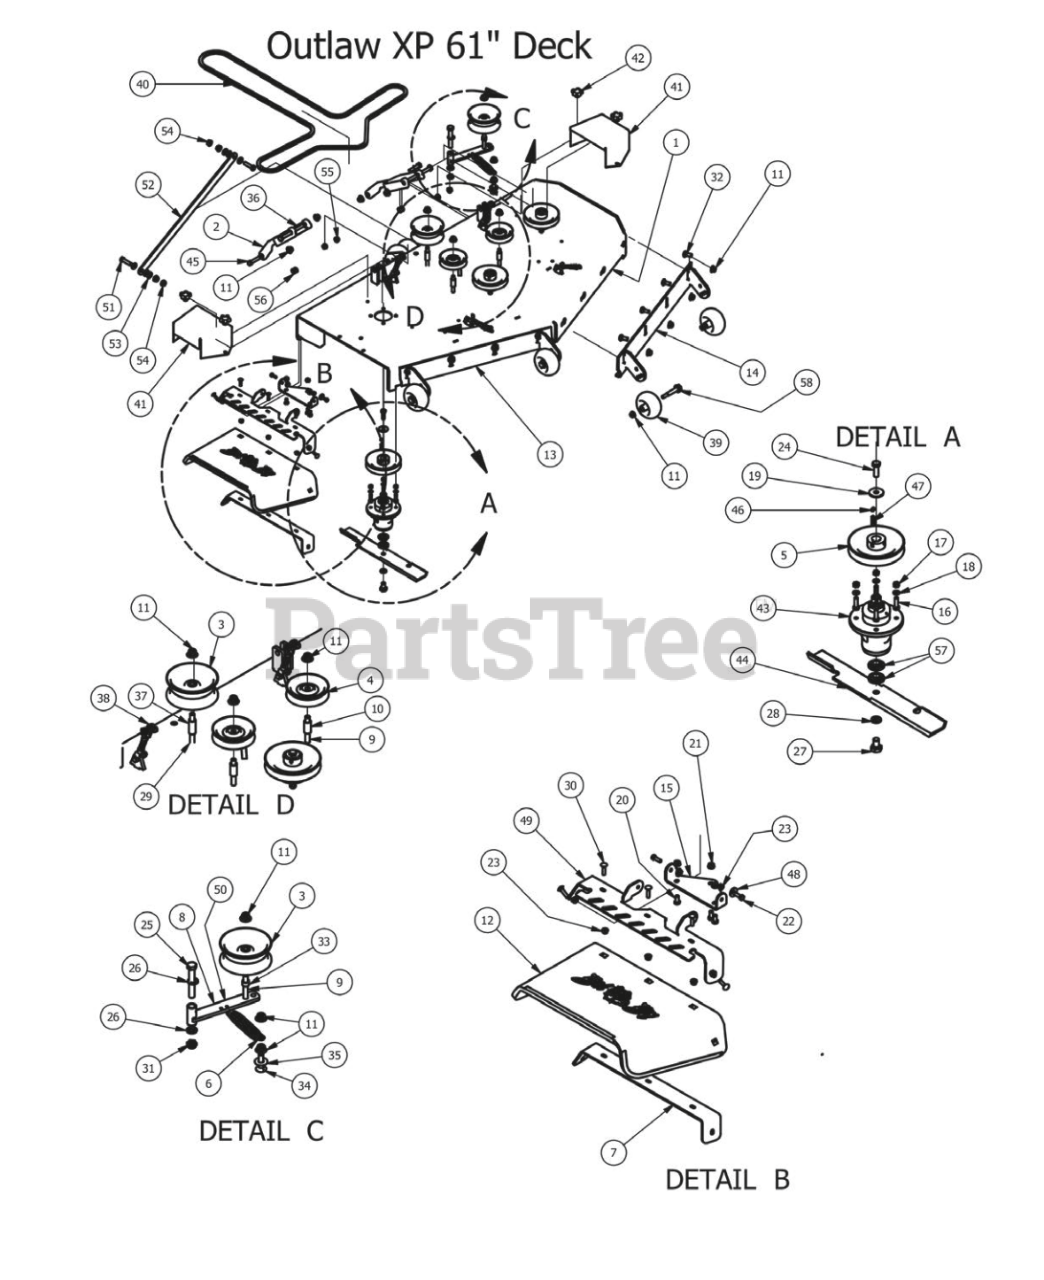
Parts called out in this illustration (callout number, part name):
1	61" Outlaw (Deck Only)
2	Deck Arm Assembly
3	5 3/4 Flat Idler-32FI-92-008 Pulley
4	4 3/4" Idler Pulley
5	6 1/4" Drive Pulley
6	2009 Deck/Pump Idler Spring
7	60" Lower Hanger
8	Deck Idler Bracket
9	1/2 x 3 1/2 Flange Bolt Grade 8
10	Pulley Spacer
11	1/2-13 Nylon Insert Flange Nut
12	Rubber Discharge Chute
13	61 Outlaw Adjustable Deck Front (Left)
14	61 Outlaw Adjustable Deck Front (Right)
15	Discharge Chute Hanger (deck mounted)
16	3/8" x 1 1/4" Hex Bolt
17	3/8-16 Hex Nuts Zinc
18	3/8 Lockwasher Zinc
19	1/2 Belleville Washer
20	3/8" x 3/4" Hex Bolt
21	3/8" Flange Nut
22	5/16" x 1" Bolt
23	5/16" Flange Nut Zinc W/Serrations
24	1/2"-20 x 1 1/2 Grade 5 Fine Thread Bolt
25	5/8" x 4" Hex Bolt
26	.635 ID Plastic Washer
27	5/8" x 1 1/2" Grade 8 Bolt
28	5/8" Lock Washer
29	1/2" x 4" Bolt (Grade 8)
30	5/16" x 1 1/4" Carriage Bolt
31	5/8" Nylock (1/2 Jam)
32	1/2" x 1 1/4 Carriage Bolt
33	Spacer 3/4 OD X 1/2 ID x .75
34	1/2 x 2" Carriage Bolt
35	1/2" Flat Washer
36	1/2" x 5 1/2" Bolt
37	1 3/4" Pulley Spacer
38	3- Link Adjustable Deck Hange
39	Deck Wheel
40	B178 Belt For 61 Inch Outlaw
41	Pulley Cover
42	5/16" Knob
43	Double Bearing Spindle
44	61 inch Fusion Blade
45	1/2-13X 2-1/4 GR Hex Bolts
46	5/16 Set Screw
47	1/4" x 1" Key
48	.360 ID Plastic Washer
49	60" Upper Hanger Plate
50	Deck Idler Assembly-parts of Assembly 8,11,3,33,9
51	1/2" x 13-2" GR 5 Hex Bolt
52	Panhard Linkage Bar
53	.505 Nylon Spacer
54	1/2" Flange Nut
55	Flange Bushing For Deck Arm upper
56	Flange for Lower Deck Arm
57	Double Bearing For Spindle
58	Deck Wheel Bolt-2011 Outlaw
